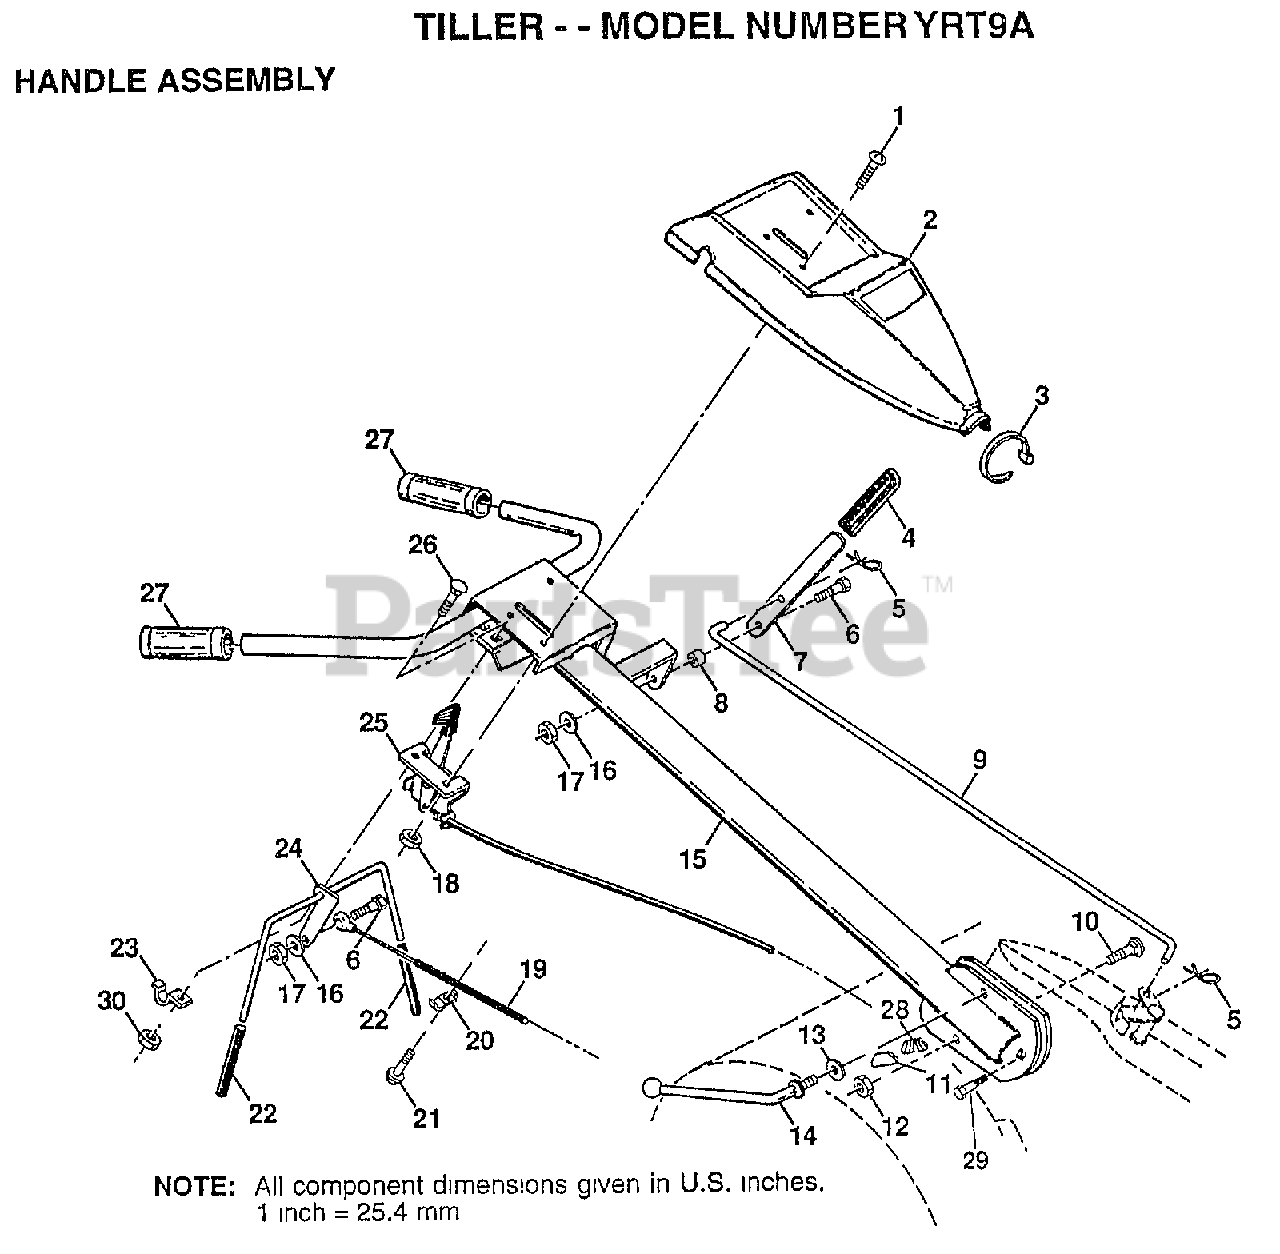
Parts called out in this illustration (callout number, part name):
1	SCREW.PNHD.10-24
2	"PANEL,CONT TI"
3	TIE CABLE CRT
4	GRIP T
5	RETAINER M
6	SHOULDER BOLT ST
7	SHIFT HANDLE CRT
8	GROMMET CRT
9	ROD.SHIFT
10	BOLT D
11	LOCK CRT
12	LOCKNUT
13	WASHER CRT
14	LEVER LOCK CRT
16	LOCKWASHER
19	CABLE-CLUTCH CRT
20	CONDIUT CLIP T
22	GRIP BAR CRT
24	"ASSY CONTROL, BAR"
25	CONTROL.THROTTLE
26	BOLT
28	LOCK.HANDLE
29	BOLT PIVOT
30	NUT
